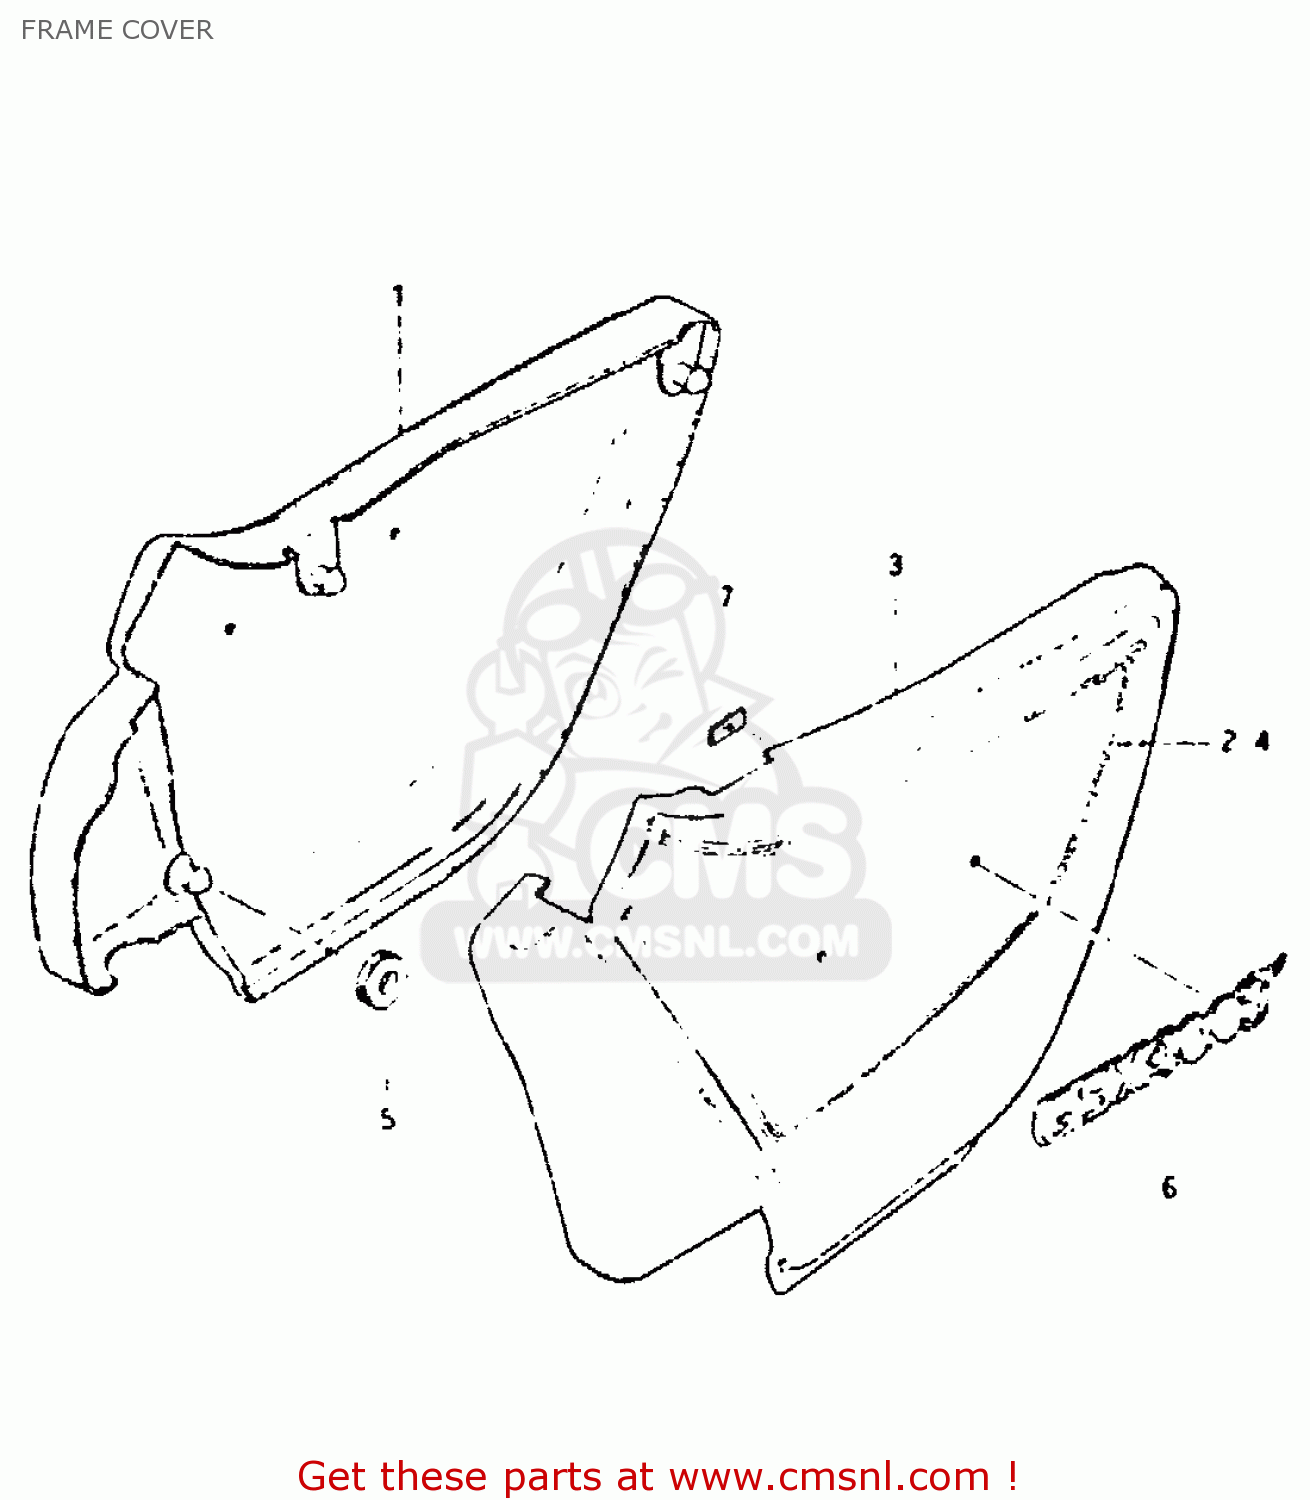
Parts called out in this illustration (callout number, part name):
1	COVER,FRAME,RIGHT
2	TAPE SET,FRAME COVER
3	COVER,FRAME,LEFT
4	TAPE SET,FRAME COVER
5	CUSHION
6	EMBLEM
7	NUT
